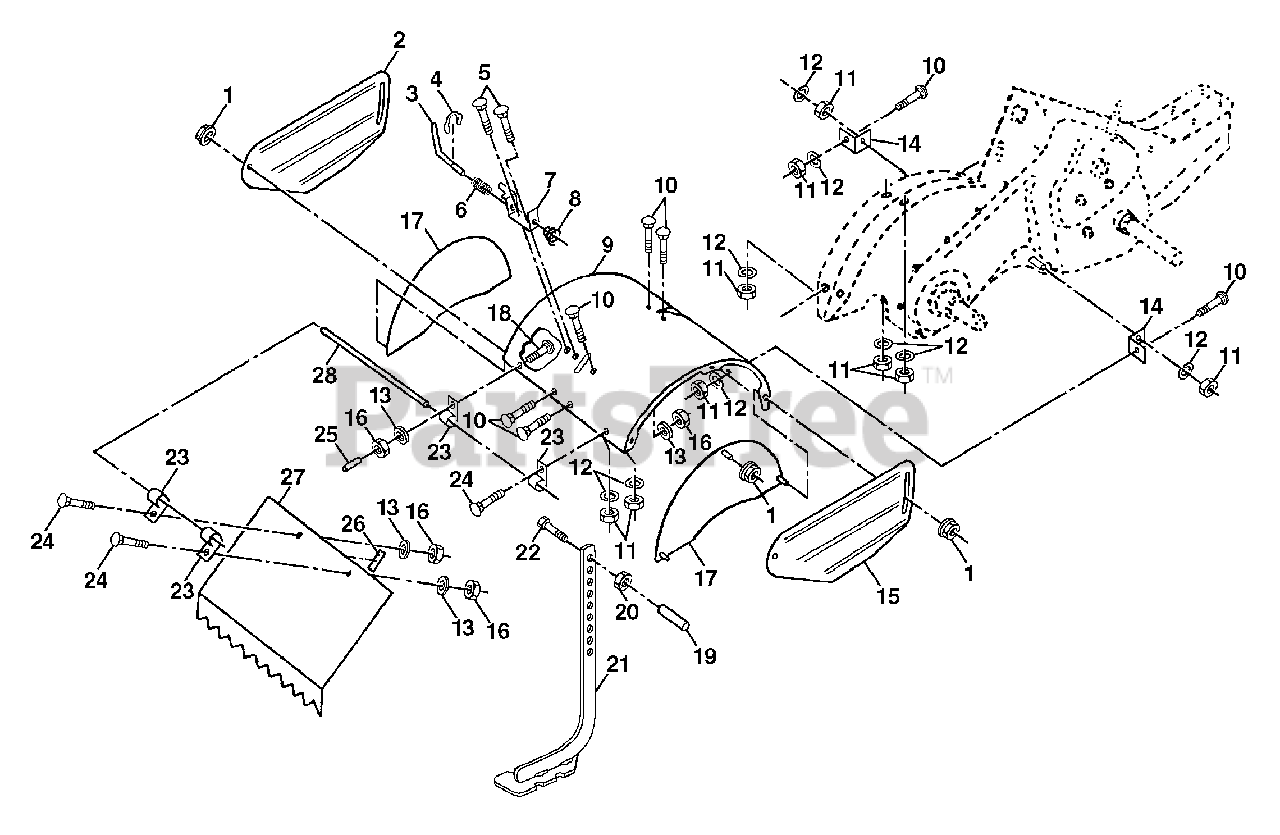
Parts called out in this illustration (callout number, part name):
1	Nut, Flange 5/16-18
2	Shield, Side, Outer, L.H.
3	Pin, Depth Stake
4	Ring, Klip
5	Bolt, Carriage 5/16-18 x 1
7	Bracket, Latch
8	Spring, Depth Stake
9	Shield, Tine
10	Bolt, Carriage 5/16-18 x 3/4 Gr. 5
11	Nut, Hex 5/16-18
12	Washer, Lock 5/16
13	Washer, Lock 1/4
14	Bracket, Shield Tine
15	Shield, Side, Outer R.H.
16	Nut, Fin, Hex, 1/4-20
17	Shield, Side
18	Bolt, Carriage 1/4-20 x 1-1/4 Gr. 5
20	Nut, Hex 3/8-16
21	Stake, Depth
22	Bolt, Hex 3/8-16 x 3-1/2
24	Bolt, Carriage 1/4-20 x 1/2 Gr. 5
25	Cap, Vinyl
26	Pad, Idler
27	Shield, Leveling
28	Pin, Hinge
